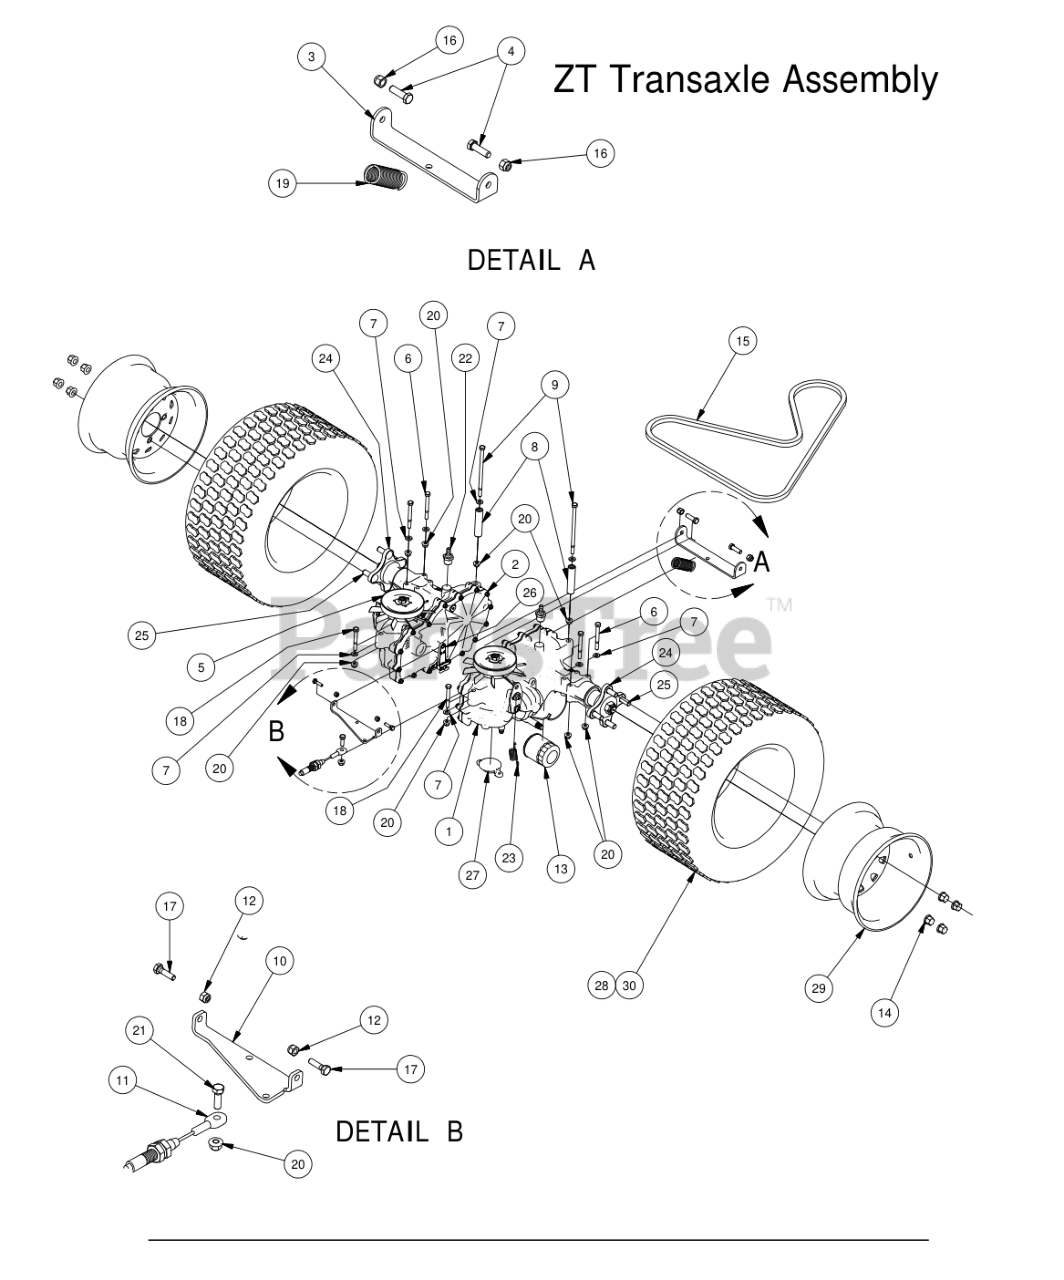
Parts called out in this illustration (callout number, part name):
1	Left ZT Transaxle
2	Right ZT Transaxle
3	Crossover Bar for ZT
4	3/8" x2" Hex Bolt
5	Fan/Pulley Kit
6	5/16" x 3" Hex Bolt
7	5/16" Flat Washer
8	3 1/4" Spacer
9	5/16" x 6" Bolt
10	ZT Crossover Brake Bracket
11	Brake Cable Stand On
12	1/4" Nylock Nut
13	Transaxle Filter
14	Acorn Lug Nut
16	3/8 Nylock Nut
17	1/4-20 x 1 GR 5 hex bolt zinc
18	5/16" x 2 1/2" Bolt
20	5/16" Nylon Flange Nut
21	5/16" x 1" Bolt
22	45 degree fitting
23	Transaxle Spring
24	ZT Transaxle Hub
25	Transaxle Wheel Studs
26	Transaxle Brake Lever
27	ZT Transaxle Charge Plate/With O'Ring
28	2014 ZT Assembly 22x11-10(Wheel and Tire)
29	2014 ZT Wheel Only 22x11-10
30	2014 ZT Tire Only 22x11-10
